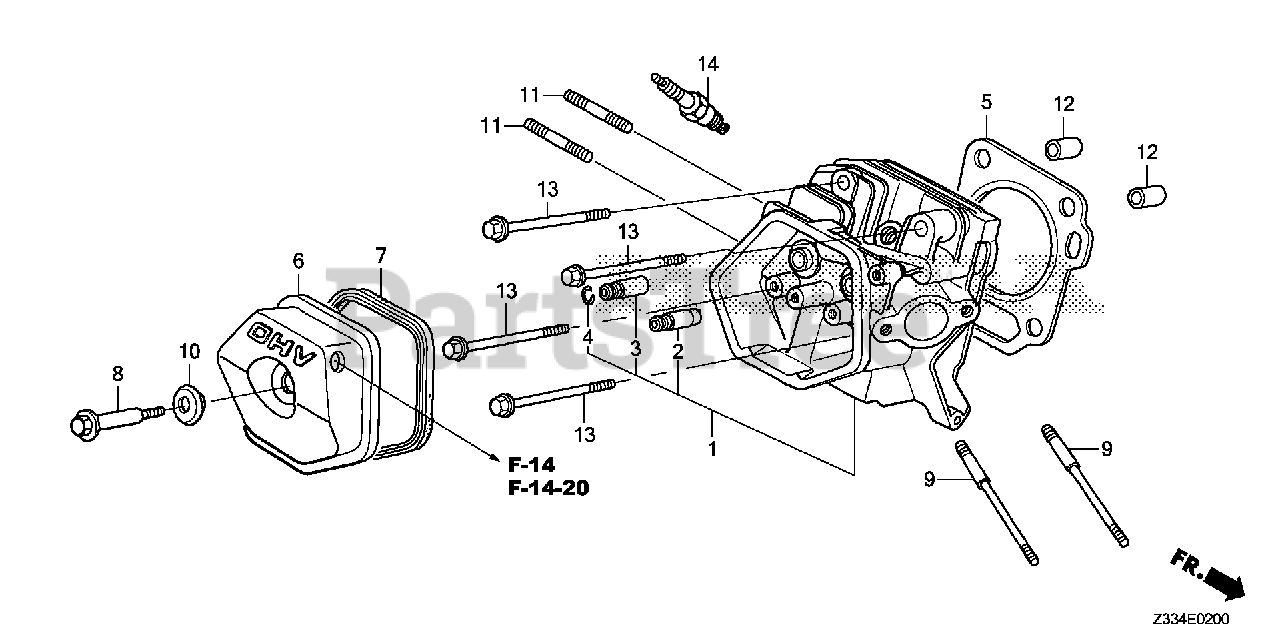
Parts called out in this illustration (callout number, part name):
1	CYLINDER HEAD
2	GUIDE, VALVE (OS)
3	GUIDE, EX. VALVE (OS)
4	CLIP, VALVE GUIDE
5	GASKET, CYLINDER HEAD
6	COVER, HEAD
7	GASKET, CYLINDER HEAD COVER
8	BOLT, HEAD COVER
9	BOLT, STUD (8X106)
10	WASHER, HEAD COVER
11	BOLT 2, STUD (8X32)
12	PIN A, DOWEL (12X20)
13	BOLT, FLANGE (10X80)
14	SPARK PLUG (BPR5ES) (NGK)
